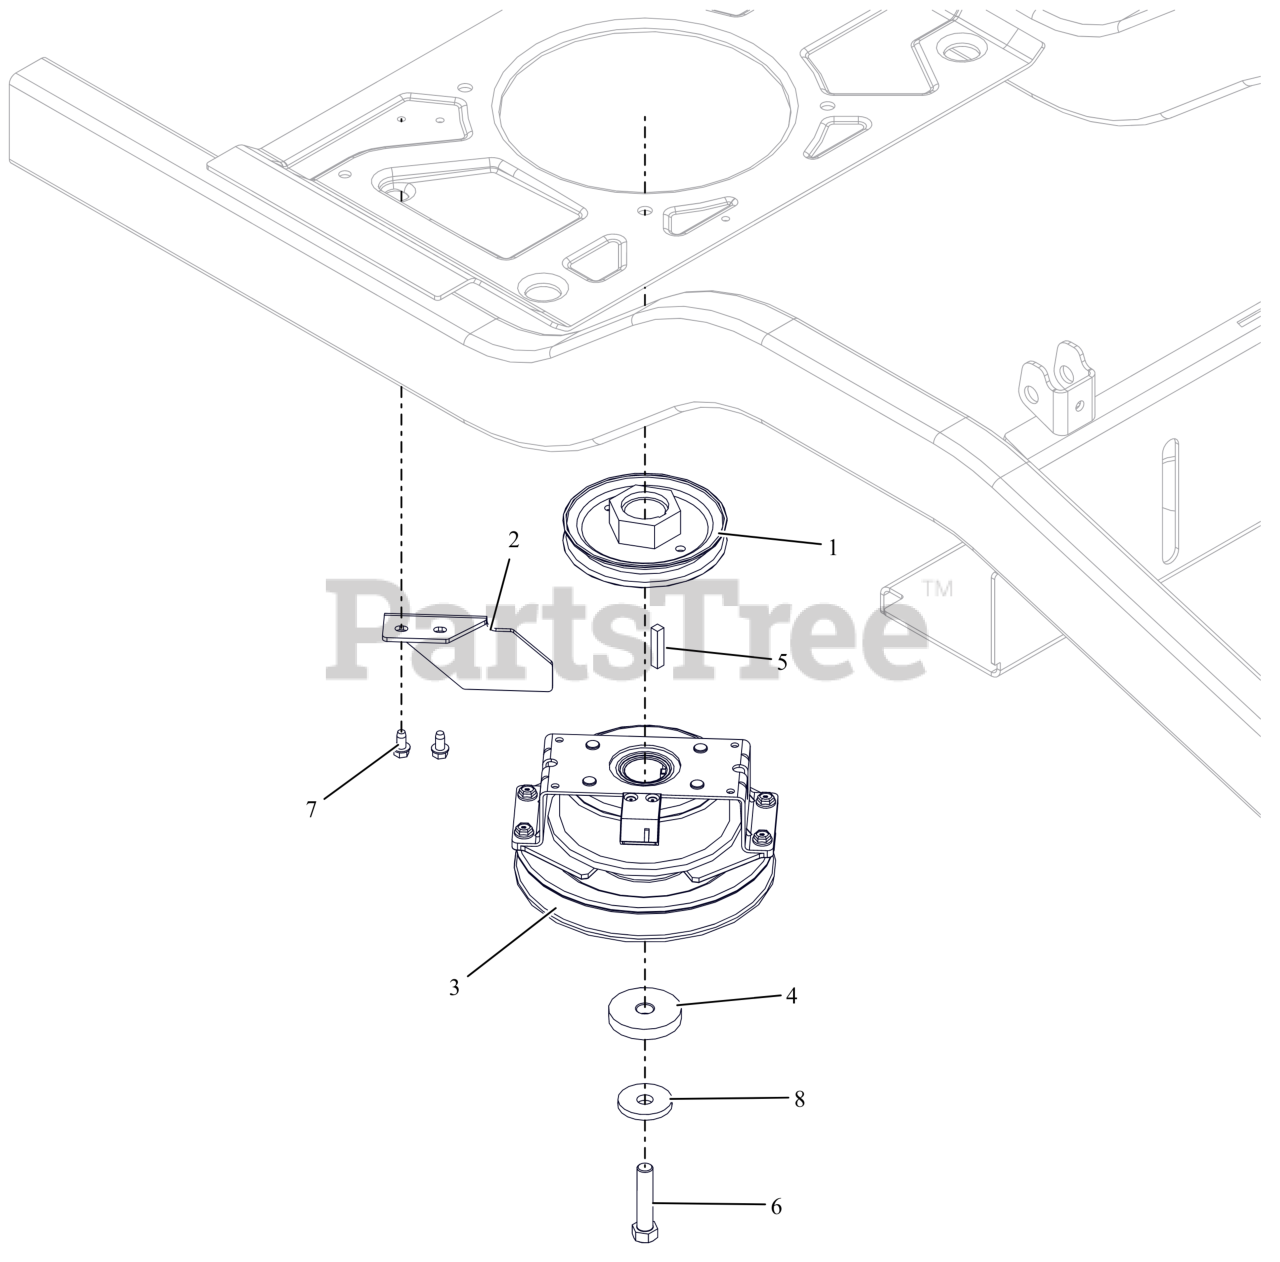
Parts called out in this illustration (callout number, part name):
1	WLDMT,PULLEY-4.50ODX1.127
2	BRKT, CLUTCH STOP HD
3	CLUTCH, OGURA DBLS SPRG 1.13"
4	SPACER, .474/.459X2.00X.350
5	KEY-SQ .25 X 1.25 X .25 SAE
6	BLT, HEX 0.4375-20X2 G8 ZCC NT
7	SCR-TAP .25-20X.50 HWH ZCC
8	WASHER, 7/16" SPRING DISK
